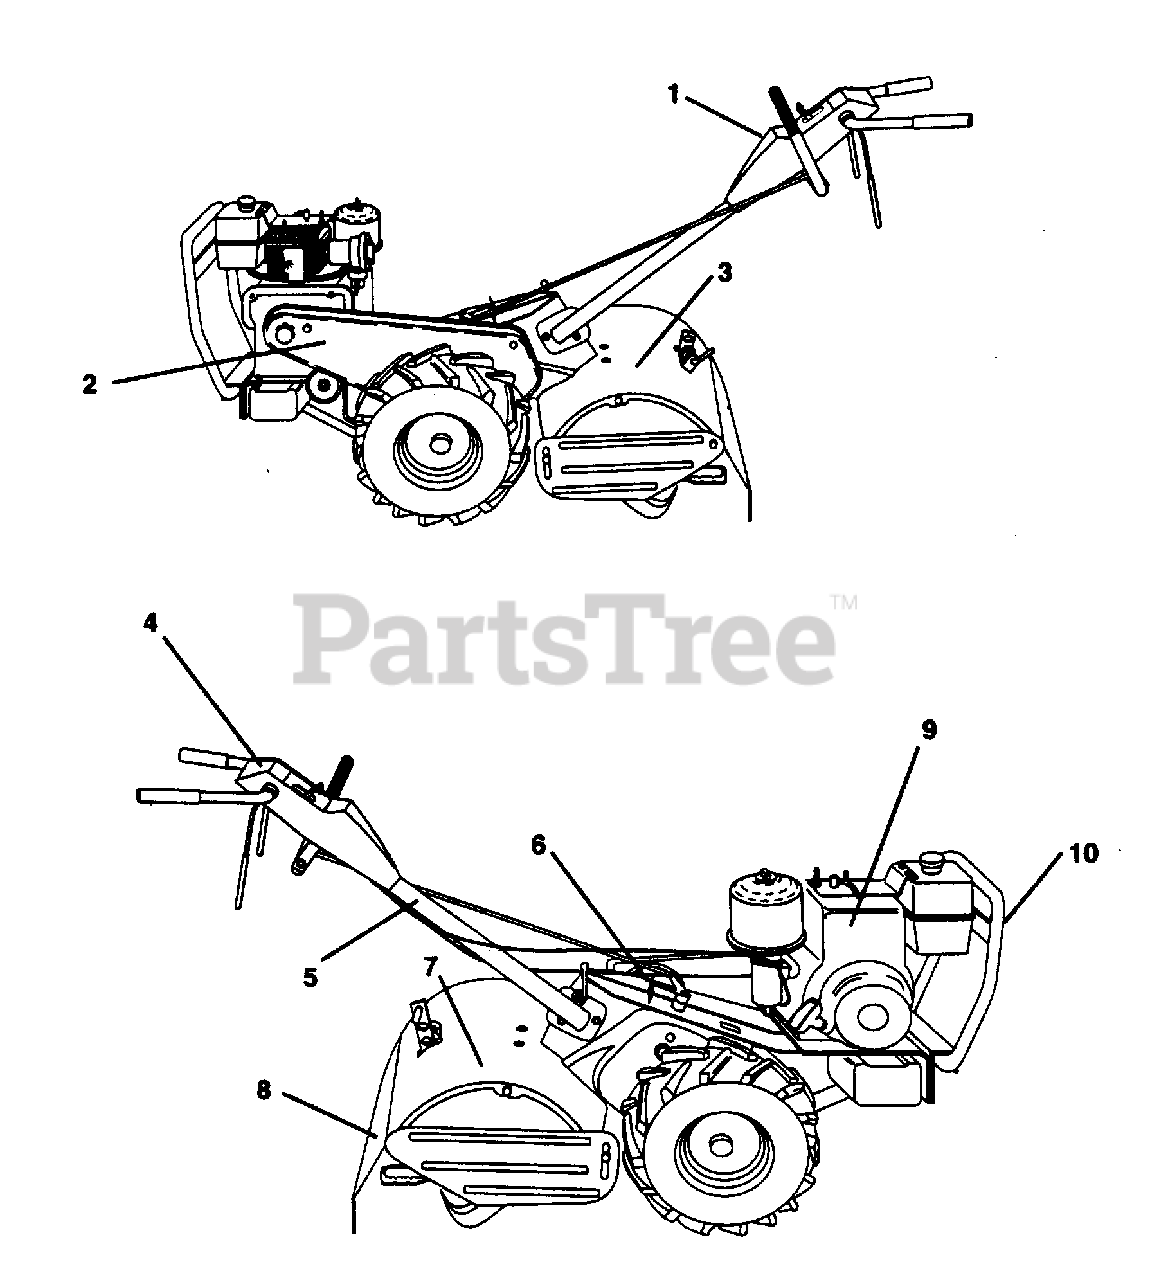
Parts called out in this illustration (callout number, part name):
1	Decal, Logo
2	Decal, Logo
3	Decal, Logo
4	Decal, Instruction, Tilling (AYP part number)
5	Decal, Hand Placement (AYP part number)
6	Decal, Shift Indicator (AYP part number)
7	Decal, Caution (AYP part number)
8	Decal, Warning, Rotating Tines (AYP part number)
9	Decal, Briggs & Statton (AYP part number)
10	Decal, Grille/Bumper
